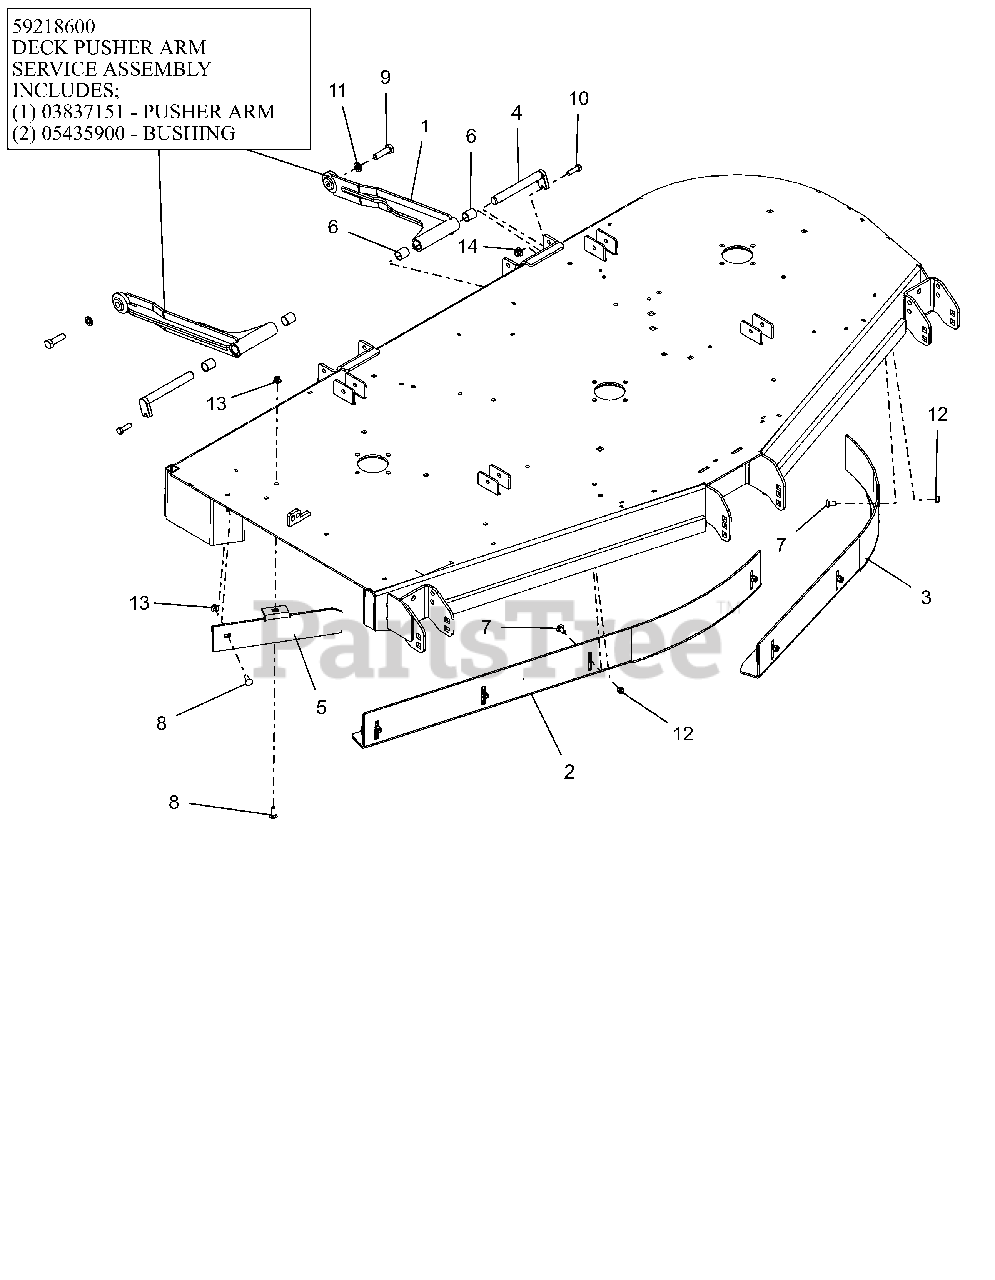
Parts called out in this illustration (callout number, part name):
1	DECK STABILIZER ARM - BLACK
1	DECK STABILIZER ARM W/BUSHINGS
2	72" RH VACUUM BAFFLE WLDMT-RED
3	72" LH VACCUM BAFFLE WLDMT-RED
4	PIN, MOWER MTG
5	72" DISCHARGE BAFFLE - RED
6	BRG, .750 X .875 X 1.000
7	@BLT-RDHDSQNK .31-18X.75 G5YZ
8	@BLT-RDHDSQNK .31-18X1.00 G5YZ
9	BLT-HEX .50-13X1.75 GR5EP80 YZ
10	@BLT-HEX .38-16X1.25 GR5 YWZC
11	@WSHR-LK .50X.125 REG YWZC
12	@NUT-LK-NYL .312-18 YWZC
13	@NUT-LK-NYL-FLG .31-18 YWZC
14	@NUT-LK-NYL-FLG .38-16 YWZC
